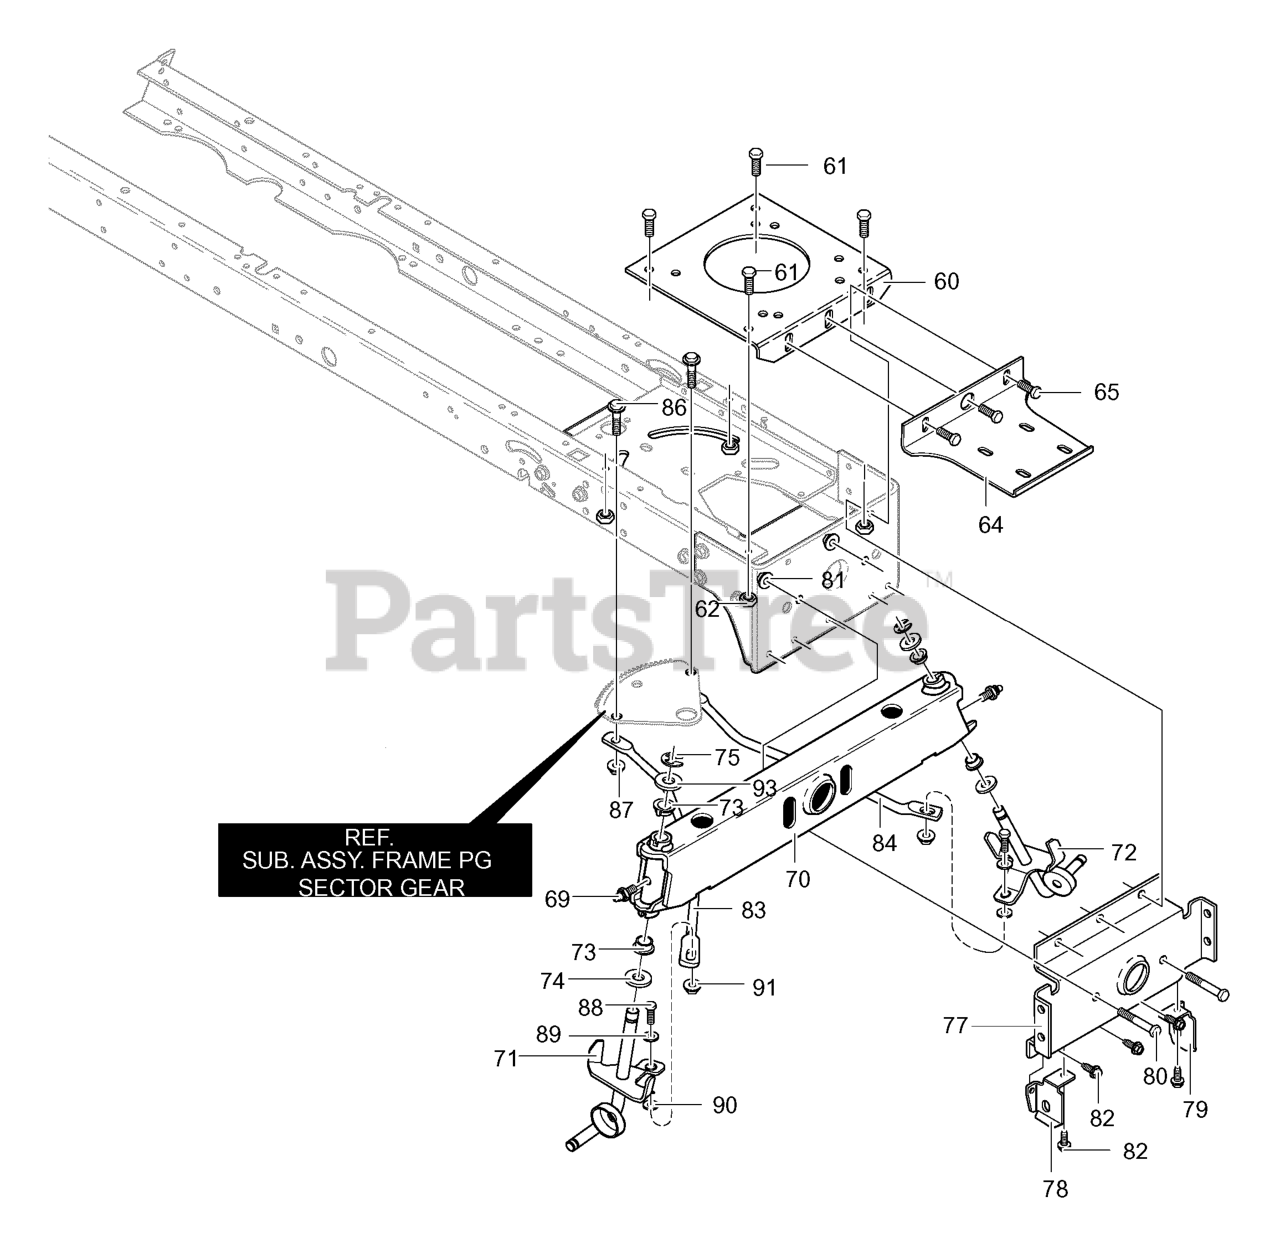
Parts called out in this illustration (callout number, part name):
60	Engine Plate
61	Screw, .312-18x.75
62	Nut, 5/16-18
64	Bracket, Muffler Mount
65	Screw, .312-18x.75
69	Zerk, Grease Fitting
70	Axle, Cast Machined
71	Spindle, RH
72	Spindle, LH
73	Bearing, Spindle
74	Washer, .766IDx1.62ID
77	Hanger, Axle
78	Hanger, Deck RH
79	Hanger, Deck LH
80	SCREW, 5/16-24 x 2.75
81	Nut, .32-24 Flangelock
82	Screw, .5/16-24X2.75
83	Drag Link, RH
84	Drag Link, LH
86	Shoulder Bolt
87	Nut, 3/8-16
88	Screw, 3/8-16 x 1.50
89	Flatwasher
90	Flatwasher
91	Nut, 3/8-16
93	Flat washer
